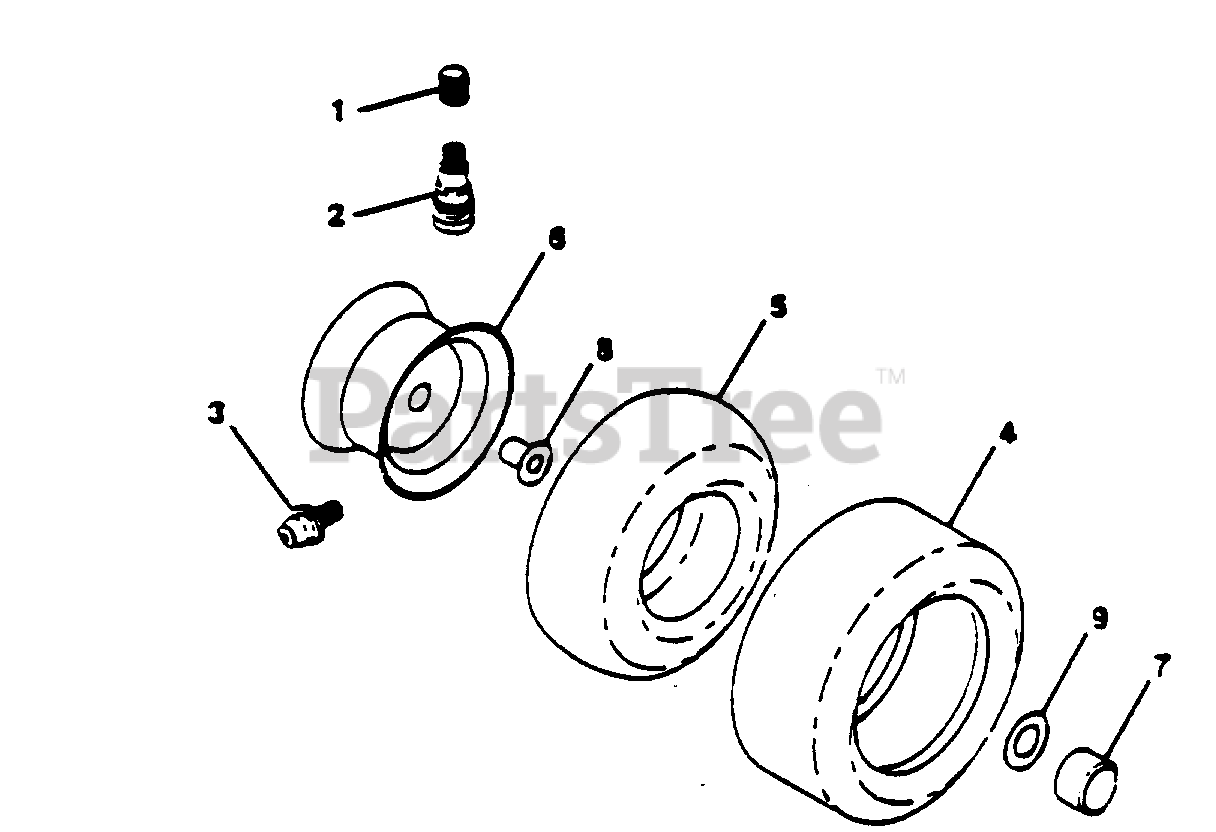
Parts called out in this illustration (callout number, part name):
1	Cap, Valve (AYP part number)
2	Stem, Valve (AYP part number)
3	Fitting, Grease (Front Wheels Only) (AYP part number)
4	Tire, Front (AYP part number)
4	Tire, Rear (AYP part number)
5	Tube, Front (Optional Service Items Only)
5	Tube, Rear (Optional Service Items Only) (AYP part number)
6	Rim, Front (AYP part number)
6	Rim, Rear
7	Cap Axle (AYP part number)
8	Bearing Flange (AYP part number)
9	Washer 25/32 x 1-5/8 x 16 Ga. (AYP part number)
